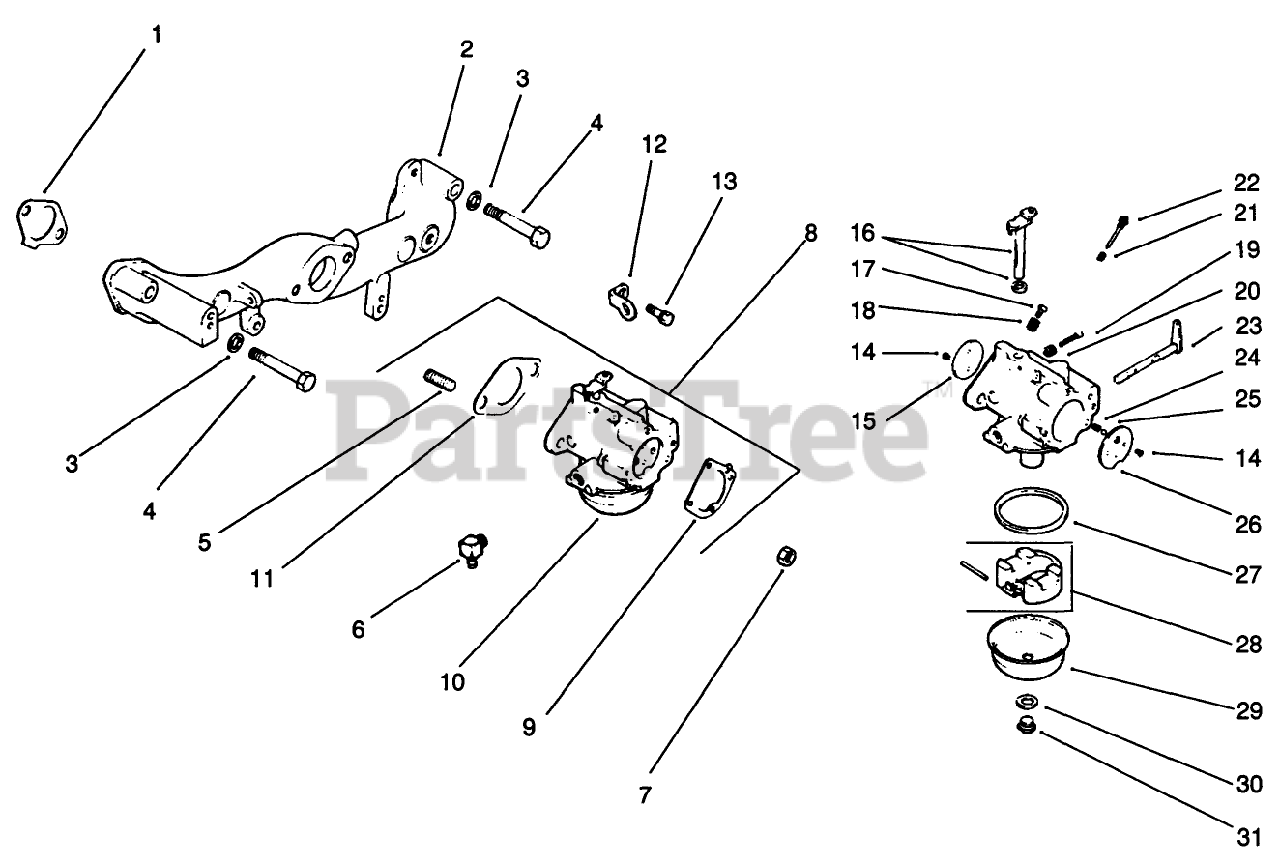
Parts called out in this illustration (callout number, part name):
1	Gasket-Intake
2	Manifold-Intake
3	Screw
4	Screw
6	Connector
8	Kit-Carburetor w/Gasket
9	Gasket
10	Carburetor Assembly Ref.
11	Gasket
12	Strap Lifting
13	Screw
14	Screw-Throttle Plate (Only On: 72042,72043,72062,72063)
15	Plate-Throttle
16	Shaft Assembly
17	Needle-Idle Fuel Adj.
19	Screw-Idle Speed Adj.
20	Spring-Idle Speed
22	Needle-Main Fuel
23	Lever-Choke
24	Spring-Choke Friction
25	Ball-Choke Friction
26	Plate-Choke
27	Gasket
28	Kit-Float
29	Bowl-Fuel
30	Gasket-Retainer Screw
31	Screw-Bowl Retainer
